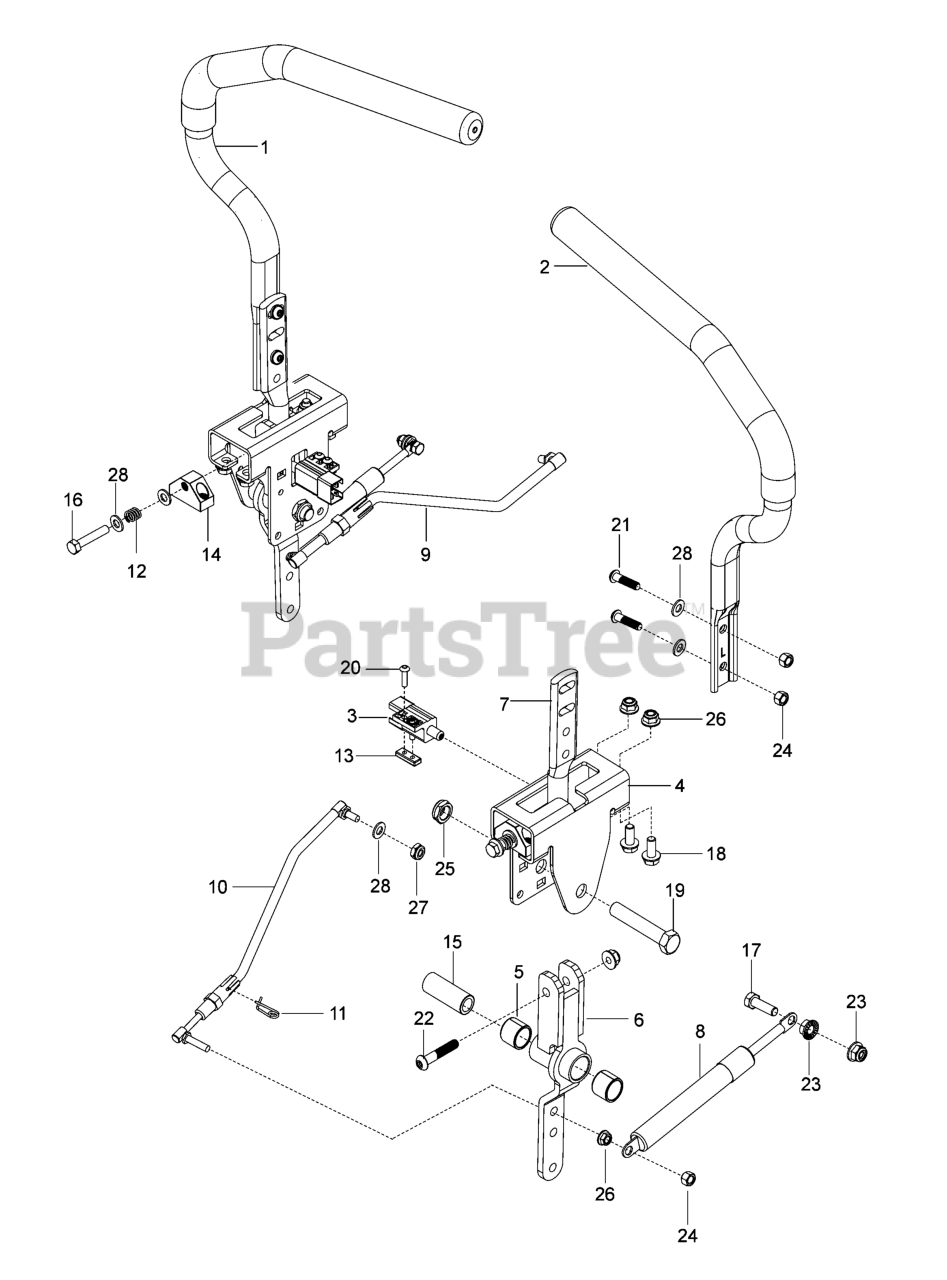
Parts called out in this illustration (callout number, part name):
1	LEVER, Right
2	LEVER, Left
3	SWITCH, Neutral
4	BRACKET, Control
5	BUSHING (Control Lever)
6	LEVER, Control
7	LEVER, Control
8	DAMPENER
9	ROD, Control, Right
10	ROD, Control, Left
11	Retainer Clip Spring Steering
12	SPRING, Lever
13	PLATE, Switch
14	STOP, Block
16	Bolt Full Thd 5/16-18 x 1-1/4
17	CAPSCREW, 5/16-18 X 1
18	SCREW, Flange, 5/16-18 X 3/4
19	CAPSCREW, 1/2-13 X 2-3/4
20	SCREW, 10-24 X 3/4 SOCKET HEAD
21	SCREW, 5/16-18 X 1-1/4 BUTTON HEAD
22	SCREW, 5/16-18 X 1-3/4 BUTTON HEAD
23	NUT, 5/16-18 HEX WHIZ LOCK
24	Nut, Lock 5/16-18 unc
25	LOCKNUT, 1/2-13 HEX JAM NYLOC
26	LOCKNUT, 5/16-18 HEX FLANGE NYLOC
27	NUT, 5/16-18 THIN
28	WASHER, 11/32 x 11/16 x 16 Ga.
